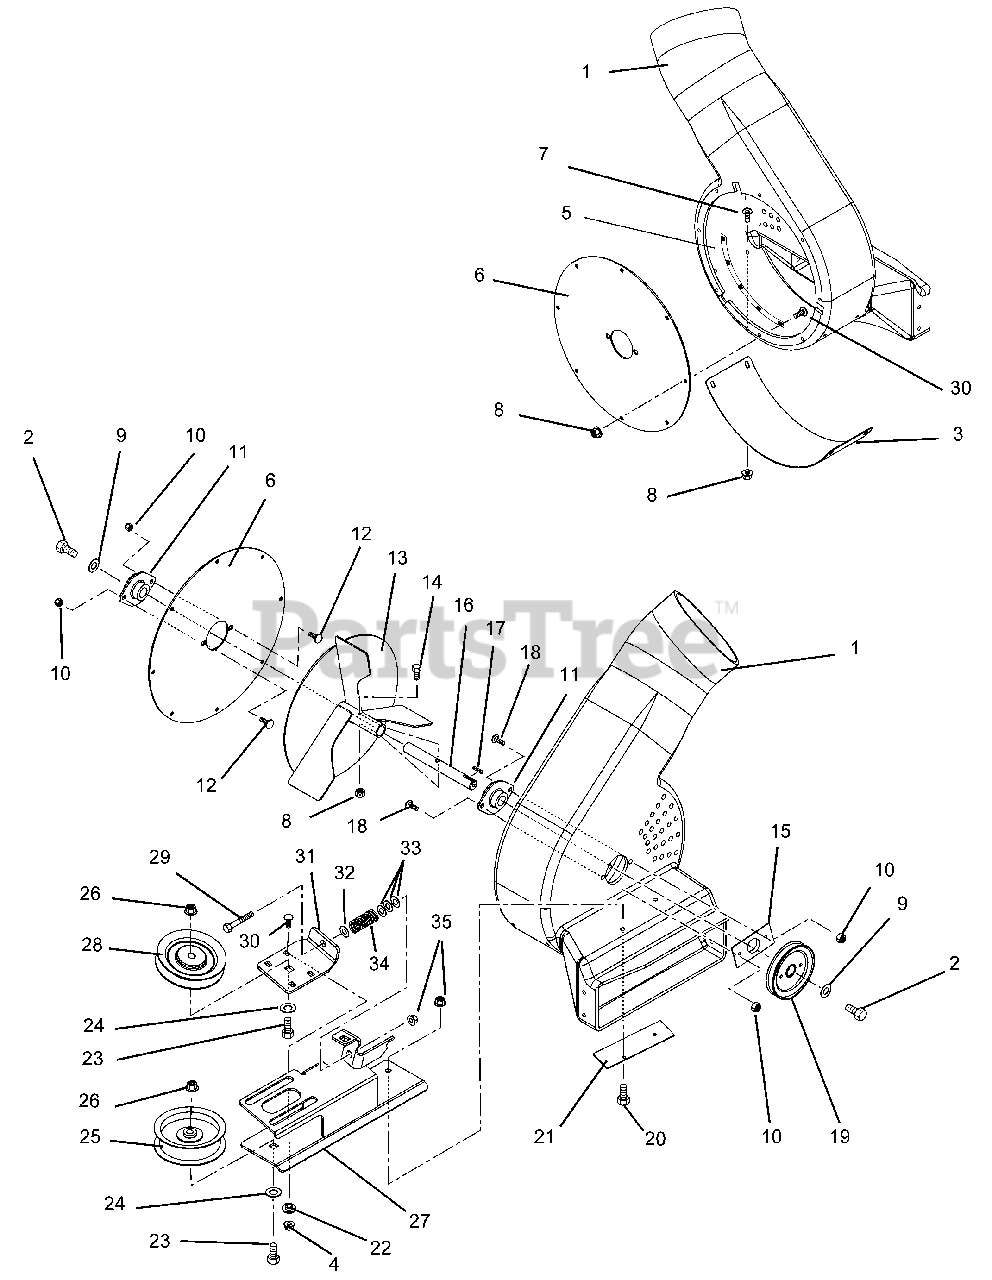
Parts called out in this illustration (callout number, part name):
1	Housing, Blower
2	Bolt, Hex .25-20 x .50
3	Plate, Skid
4	Nut-Locking-Top-Flange .25-20
5	Plate, Mounting Bolt Reinforcing
6	Plate, Bearing Mount
7	Screw-Machine .25-20 x .75
8	Nut, .25-20 Nyloc Flange
9	Washer-Flat-Steel .344 x 1.125 x .135
10	Nut-Nyloc Flange .312-18
11	Bearing, 2 Bolt Flange - .75 ID
12	Bolt-Round Head Square Neck .31-18 x .75
13	Weldment, Impeller, 3 Blade
14	Bolt-Hex .25-20 x 1.50 Grade 8
15	Plate, Washer Bearing
16	Shaft, Impeller
17	Key-Square .187 x .50 x .187 Hardened
18	Bolt-Round Head Square Neck .31-18 x 1.00 Grade 5
19	Sheave, Blower- 4.25 Diameter
20	Bolt-Hex .31-18 x .875 Grade 5
21	Plate, Back
22	Bushing-Flange .265 x .437 x .250 x .750
23	Bolt-Hex .38-16 x 1.75 Grade 5
24	Washer-Flat-Steel .406 x .812 x .065
25	Idler Flanged 3.50
26	Nut-Locking-Top-Flange .38-16
27	Weldment, Idler Mount
28	V-Idler, 4.00 x .38
29	Bolt-Hex .31-18 x 4.00 Grade 5
30	Bolt-Round Head Square Neck .25-20 x .75 Grade 5
31	Bracket, Adjustable Idler
32	Nut-Push .312
33	Washer-Flat-Steel .406 x 1.00 x .188
34	Spring-Compression .092 x .77 x 3.13
35	Nut-Locking-Top-Flange .31-18
36	Blower, Service Assembly (includes items 1-35)
